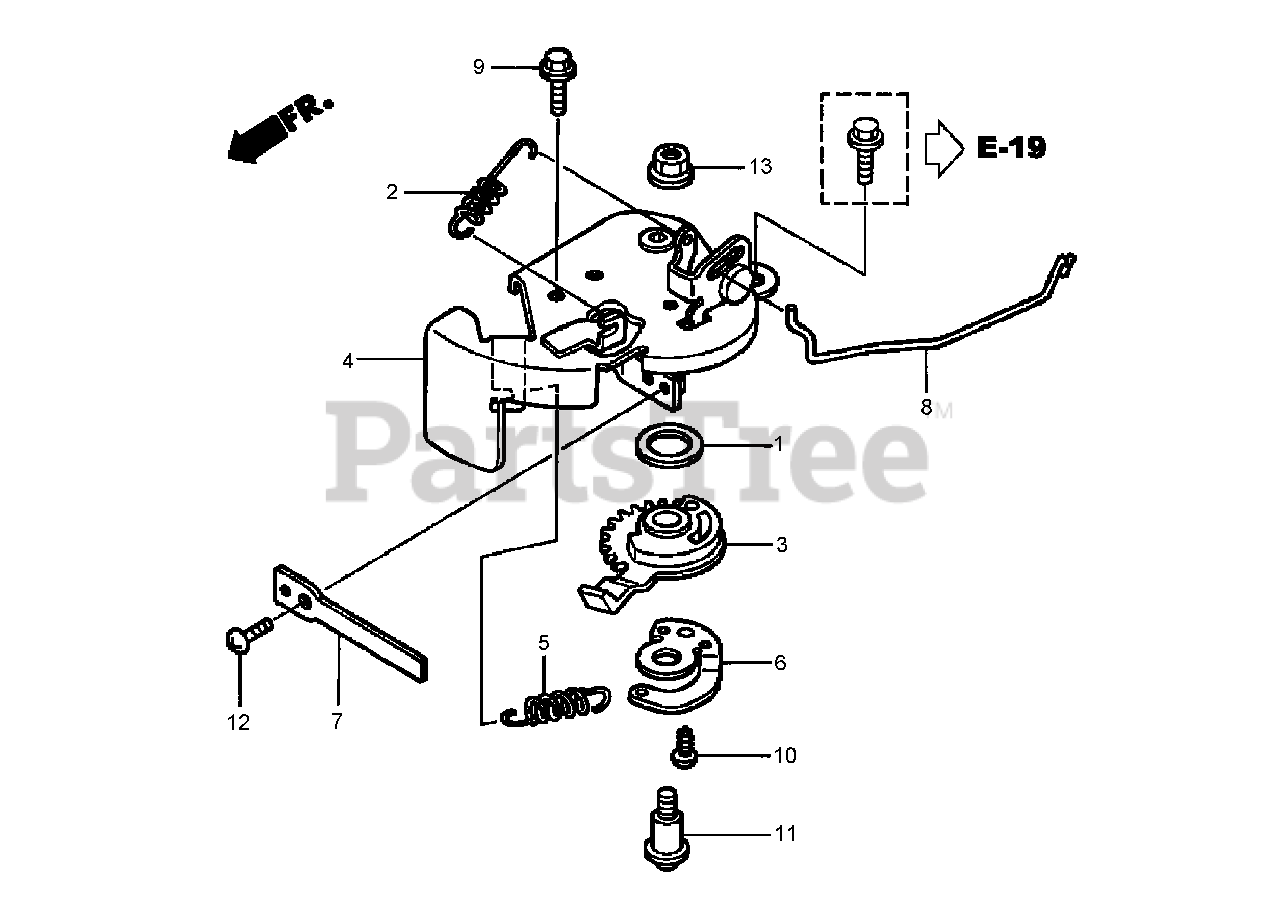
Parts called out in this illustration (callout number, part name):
1	SEAL-LEVER, CHOKE
2	SPRING-RETURN, CABLE
3	LEVER-CHOKE
4	BASE-CHOKE
5	SPRING-LEVER, CHOKE
6	HOOK-SPRING, CHOKE
7	PLATE-CHOKE
8	ROD-STOP
9	BOLT-FLANGE (6X16)
10	SCREW-TAPPING (4X8) (PO)
11	SCREW-PAN (5X19)
12	SCREW-PAN (4X8)
13	NUT-FLANGE (5MM)
